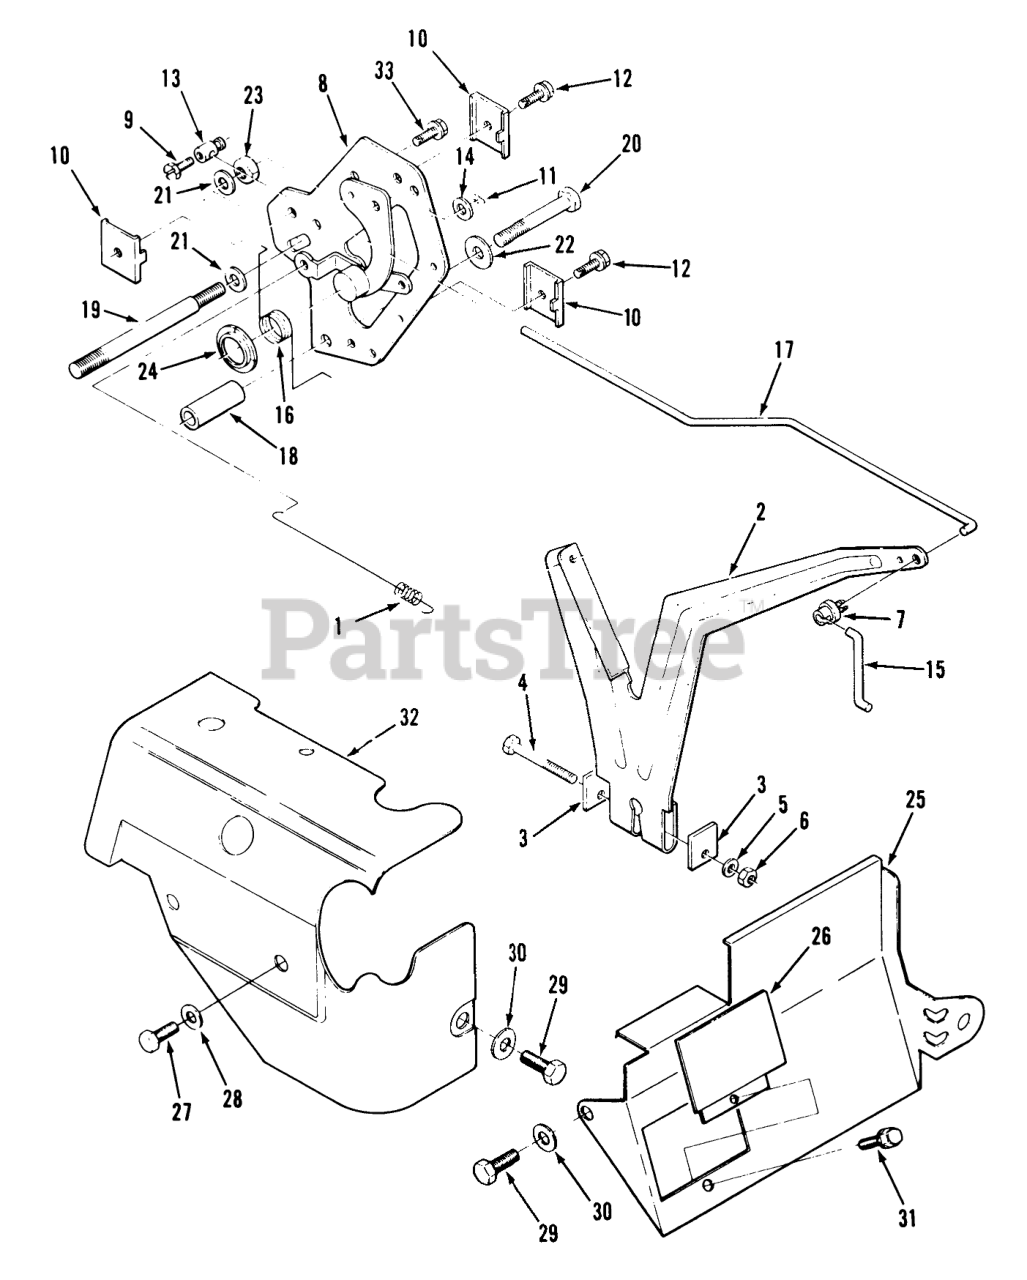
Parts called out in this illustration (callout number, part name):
1	SPRING-GOVERNOR
2	LEVER-GOVERNOR
3	WASHER
4	HHCS-M8 X 35MM
5	WASHER
6	Nut
7	Clip
8	Throttle Plate Assembly (Includes Control & Choke Levers, Pivot Pin, and Flat Washers)
9	HHMS #8-32X3/8"
10	CLAMP-CONTROL
11	Cotler Pin
12	Bolt
13	SWIVEL-CHOKE LEVER
14	Washer
15	LINK-THROTTLE
16	SPRING-CHOKE LINKAGE
17	LINK-CHOKE
18	SPACER
20	SCREW
21	Washer
22	Nut-M8
23	NUT-HEX M6
24	RING-RETAINER
25	DEFLECTOR-AIR
26	CVR-VOLT REGULATOR
27	HHCS-M8 X 10MM
28	Washer
29	HHCS-M8 X 10MM
30	Nut-M8
31	Bolt
32	Housing
33	STFHWH 12-24 X 1"
